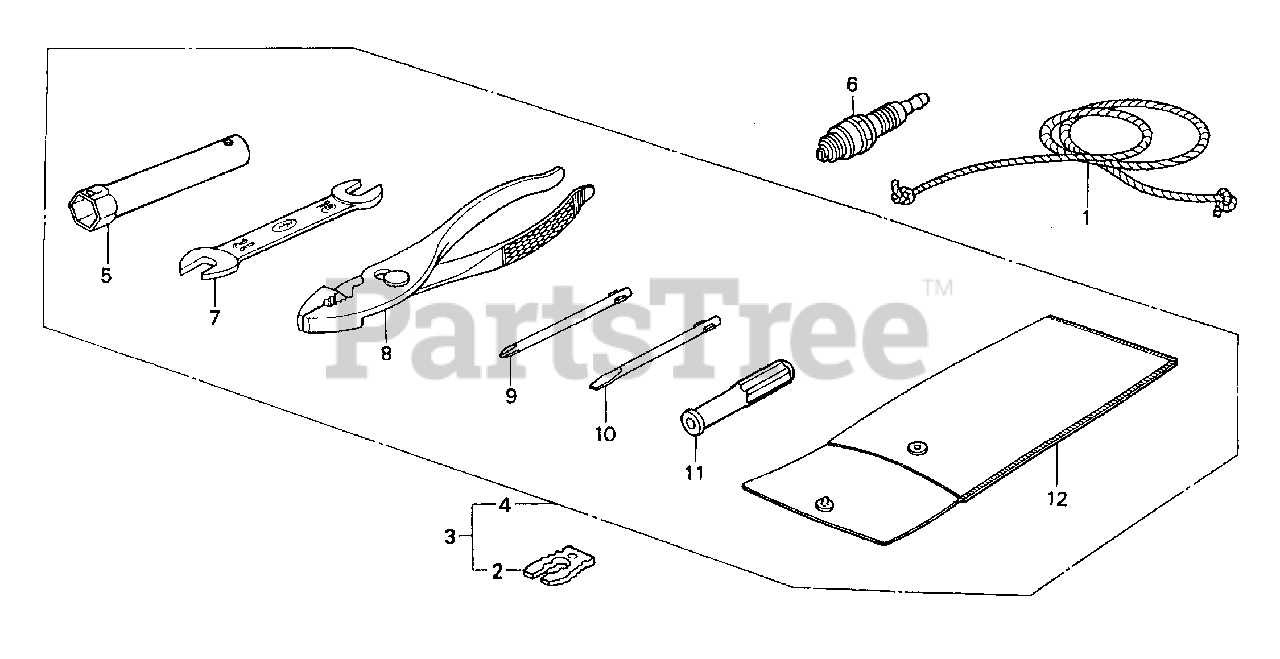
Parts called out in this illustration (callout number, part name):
1	ROPE, STARTER (#4X65") (N/A: USE ALTERNATE P/N 08540-ZG921-11)
5	WRENCH, SPARK PLUG
6	SPARK PLUG (BMR4A) (NGK)
7	WRENCH (10X12) (OPEN END)
8	PLIERS (135MM)
9	SCREWDRIVER 1, PHILLIPS (NO.2)
10	SCREWDRIVER 3, STRAIGHT SLOT (NO. 2)
12	BAG, TOOL
